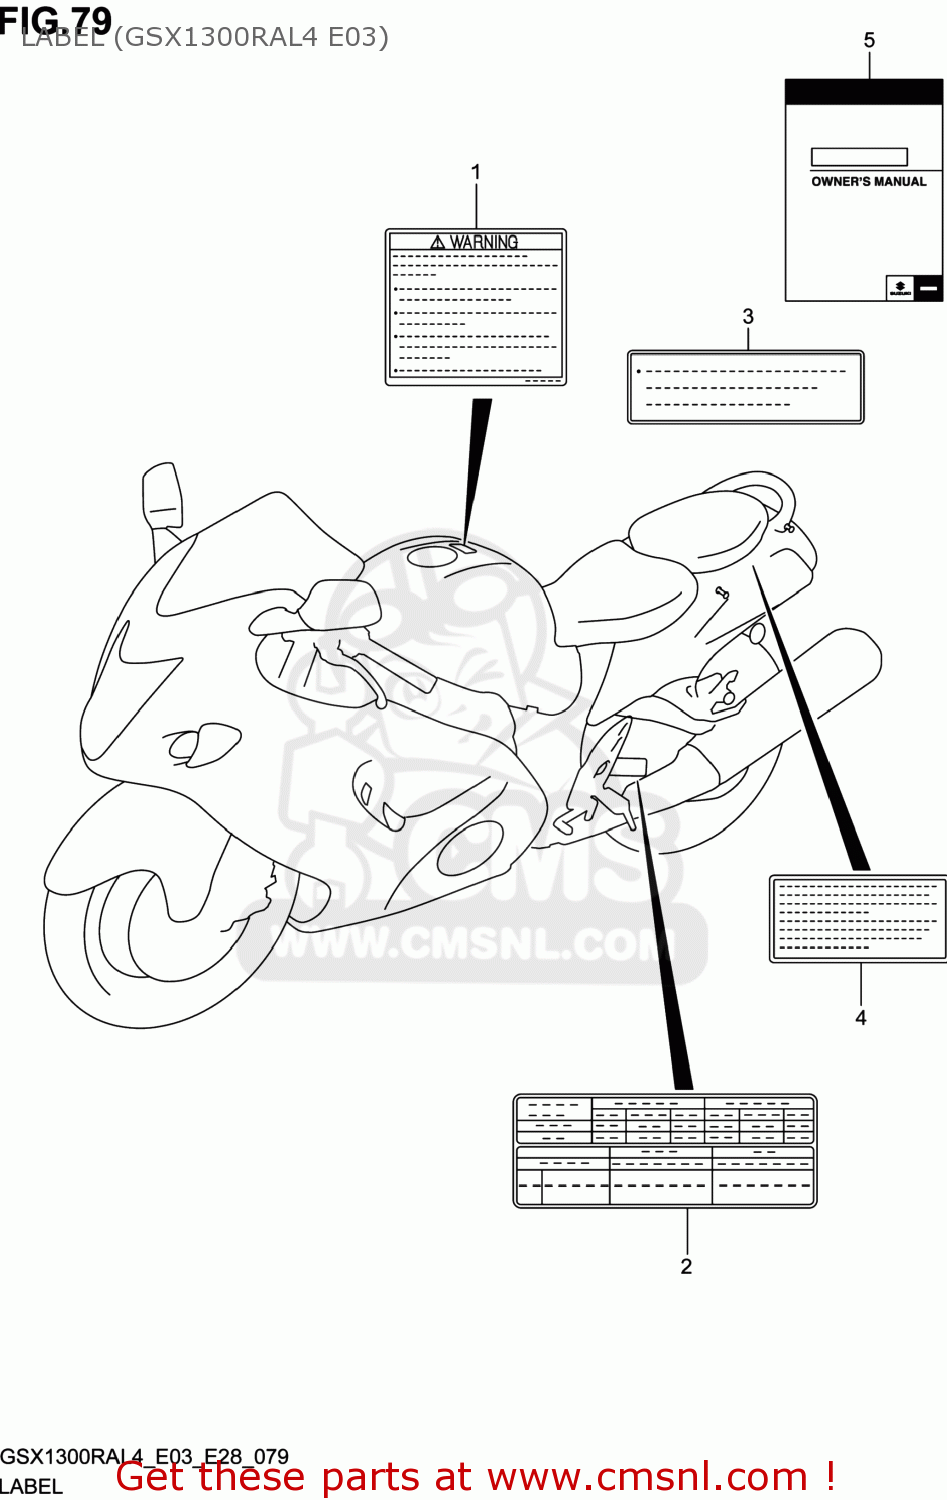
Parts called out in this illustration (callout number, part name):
1	LABEL,GENERAL WARNING
2	LABEL,TIRE INFORMATION
3	LABEL,FUEL INFORMATION
4	LABEL,MANUAL NOTICE
5	MANUAL,OWNER'S
